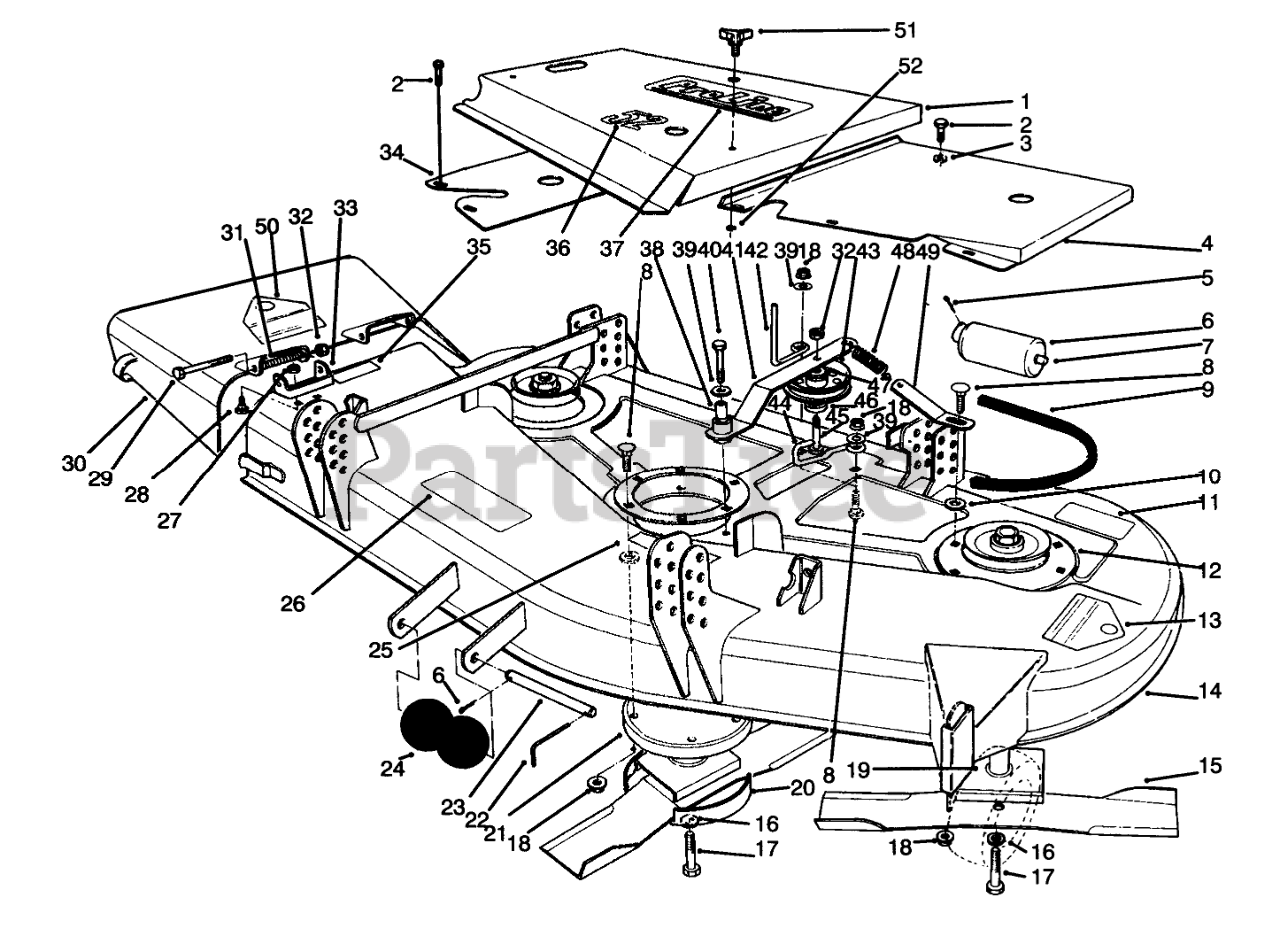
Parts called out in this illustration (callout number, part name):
1	Cover
2	SCREW-HHFTF
3	WASHER-FLAT
4	Cover
5	PIN-COTTER
6	ROLLER-DECK
7	SHAFT-ROLLER, REAR
8	SCREW-CARR
9	V-BELT
10	WASHER-FLAT
11	DECAL-TORQUE
12	SUPPORT-DECK, RING
13	DECAL-DANGER
14	Deck Assembly (Incl. Ref. #11,13,25,26,35 & 50)
15	Blade
16	WASHER-LOCK
17	SCREW-BLADE
18	NUT-HF
19	SPINDLE ASM
20	CUP-SCALP, ANTI
21	HOUSING - SPINDLE ASM
22	PIN-SPECIAL
23	SHAFT-ROLLER
24	ROLLER
25	DECAL-DANGER
26	DECAL-DANGER, THROWN OBJECT
27	NUT-LOCK, CONE
28	SCREW-CARR
29	SCREW-HH
30	Deflector-Grass (Incl. Ref.#50)
31	SPRING
32	NUT-HEX
33	Bracket-Pivot
34	Cover
35	DECAL-DANGER
36	DECAL
37	DECAL-PROLINE
38	SLEEVE
39	WASHER-FLAT
40	SCREW-HH
41	Arm-Idler
42	ROD-BELT
43	PULLEY-IDLER
44	GUIDE-BELT
45	SCREW-HH
46	BUSHING-PULLEY
47	WASHER-FLAT
48	SPRING-EXTENSION
49	PLATE-SPRING
50	DECAL-DANGER
52	RING-RETAINING
